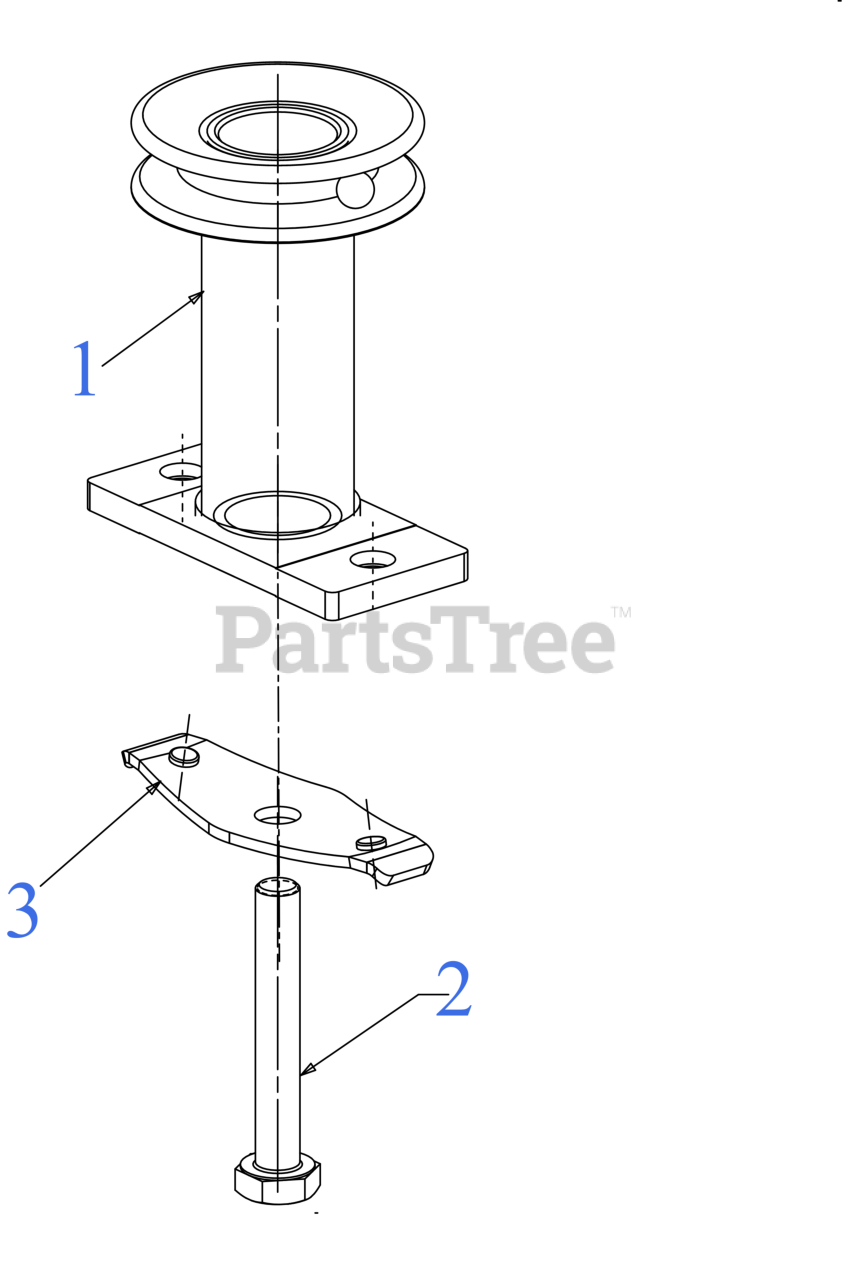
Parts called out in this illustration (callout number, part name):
1	BLADE ADAPTER (25MM x .430)
2	SCREW 3/8-24 x 2.50 GR8
3	BLADE BELL SUPPORT
